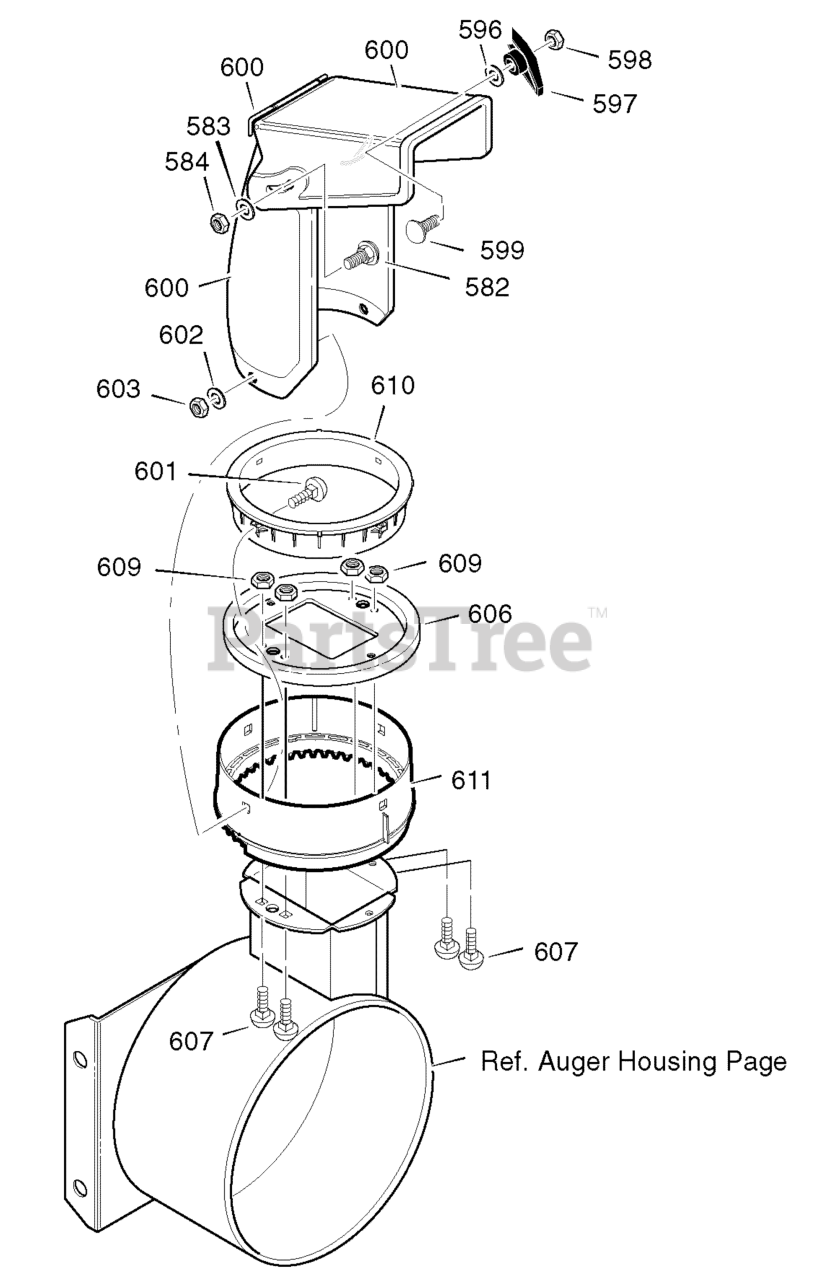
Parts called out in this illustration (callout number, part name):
582	BOLT, 5/16-18 X1.00
583	WASHER, FLAT
584	NUT, 5/16-18
596	WASHER
597	KNOB, T 3.00
598	NUT, 5/16-18 REGHEX
599	BOLT, 5/16-18 X1.50
600	CHUTE ASSEMBLY
601	BOLT, 5/16-18X1.00
602	WASHER, FLAT
603	NUT, 5/16-18 HEXNYL
606	CHUTE COLLAR
607	SCREW, 1/4-20 X 0.75
609	NUT, 1/4-20 HEX NYLOCK
610	RETAINER RING INNER
611	RETAINER RING OUTER
